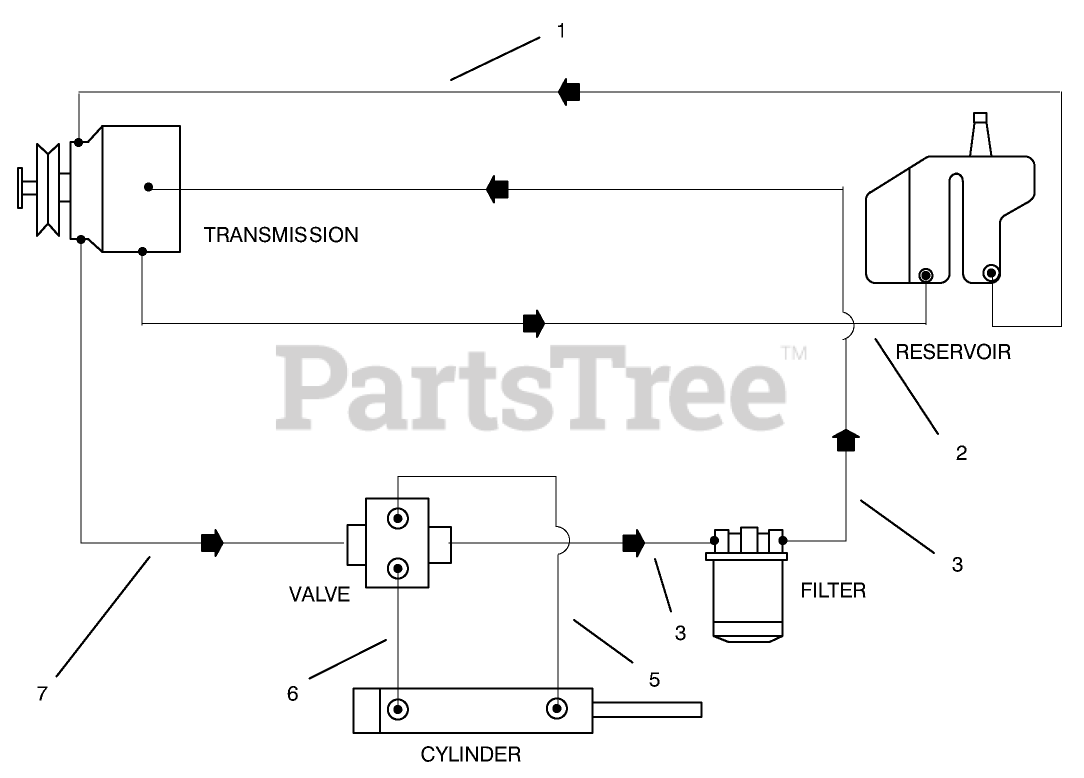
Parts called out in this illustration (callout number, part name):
1	HOSE-RESV TO PUMP
3	HOSE-ASM - HYD
5	HOSE ASM
6	HOSE ASM
7	HOSE ASM
